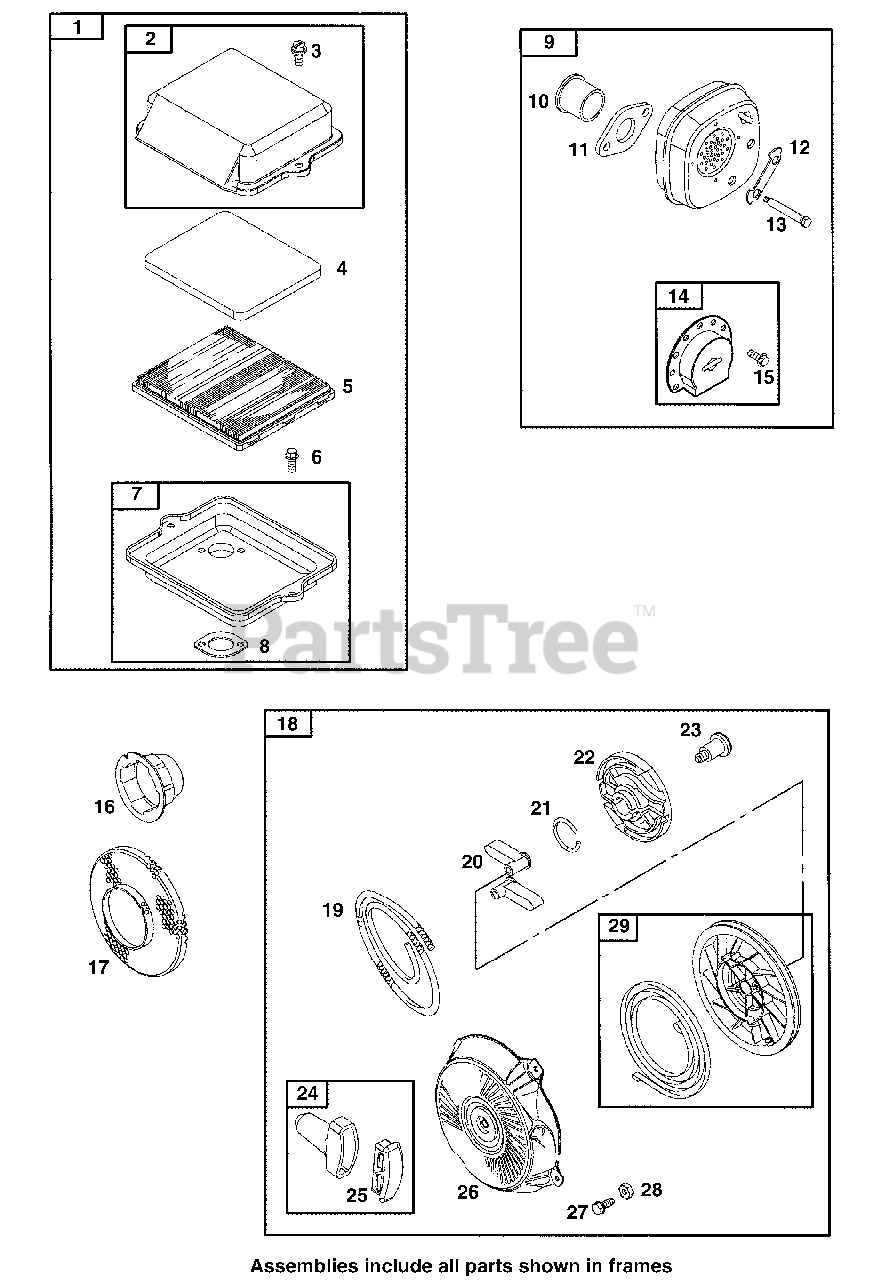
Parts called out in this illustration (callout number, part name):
1	Air Cleaner
2	Air Cleaner Cover
3	Slotted Screw
4	Pre-Cleaner Filter
5	A/C Cartridge Filter
6	Hex Screw
7	A/C Metal Base
8	Air Cleaner Gasket
9	Exhaust Muffler
10	Port Liner
11	Exhaust Gasket
12	Muffler Screw Lock
13	Shoulder Screw
14	Muffler Deflector
15	Hex Screw
16	Flywheel Cup
17	Rotating Screen
18	Rewind Starter
19	Starter Rope
20	Ratchet Pawl
21	Friction Spring
22	Pawl Friction Plate
23	Shoulder Screw
24	Starter Rope Grip
25	Grip Insert
26	Rewind Starter Housing
27	Hex Screw
28	Hex Nut
29	Starter Pulley
